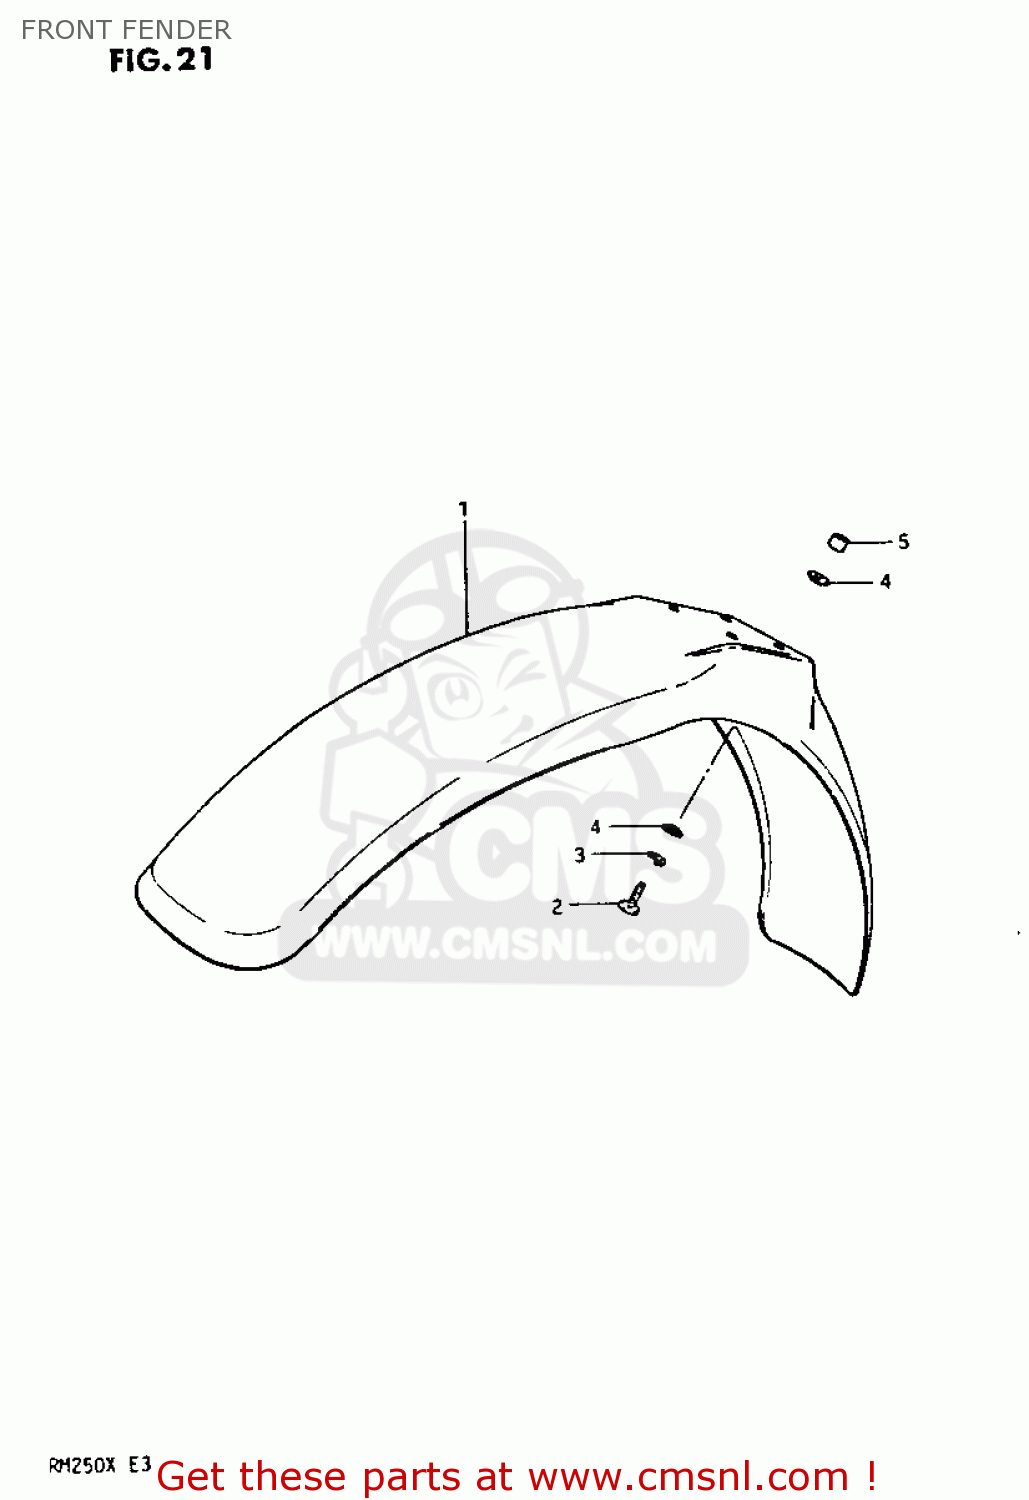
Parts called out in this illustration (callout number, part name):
1	FENDER,FRONT
2	BOLT
3	WASHER,LOCK
4	WASHER
5	SPACER FRONT FENDER
